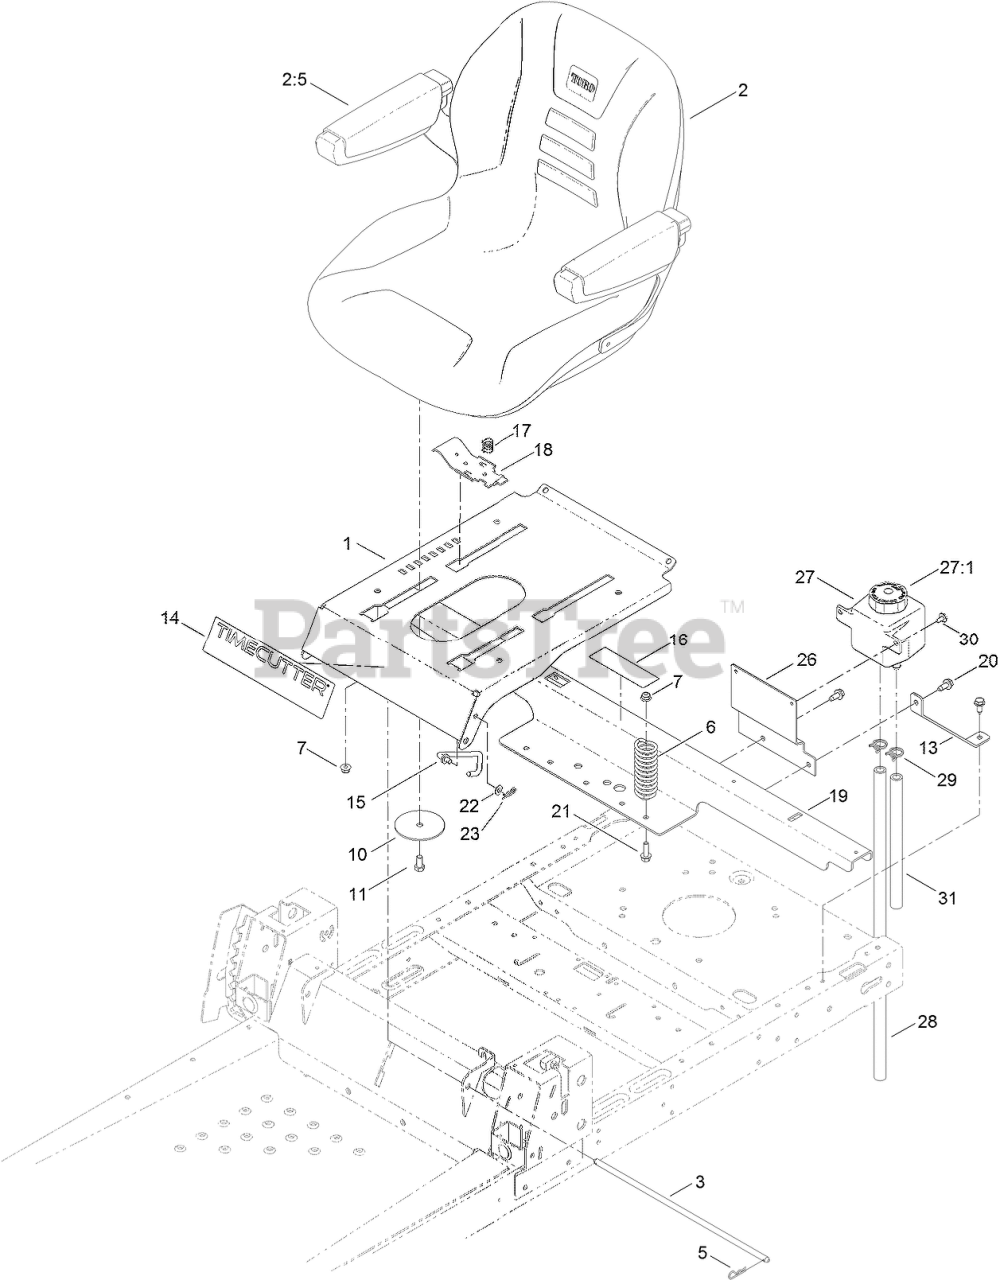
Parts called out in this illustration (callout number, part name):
1	PAN-SEAT
2	18 INCH SEAT ASM
2:5	ARMREST KIT
3	ROD-STOP
5	PIN-COTTER
6	SPRING-COMPRESSION
7	NUT-HF, NI
10	WASHER-SEAT
11	SCREW-HH
13	SUPPORT-TANK, REAR
14	DECAL-TIMECUTTER
15	STOP-SEAT
16	DECAL-SERVICE, CE
17	SPRING-COMPRESSION
18	LATCH-SEAT
19	SUPPORT-POD
20	SCREW-HWHTF
21	SCREW-HHF
22	WASHER-PLAIN
23	PIN-COTTER
26	MOUNT-TANK
27	VENT-TANK, HYD
27:1	CAP-RESERVOIR, HYD
28	HOSE-OVERFLOW
29	CLAMP-HOSE
30	SCREW-HHFTF
31	HOSE-OVERFLOW
